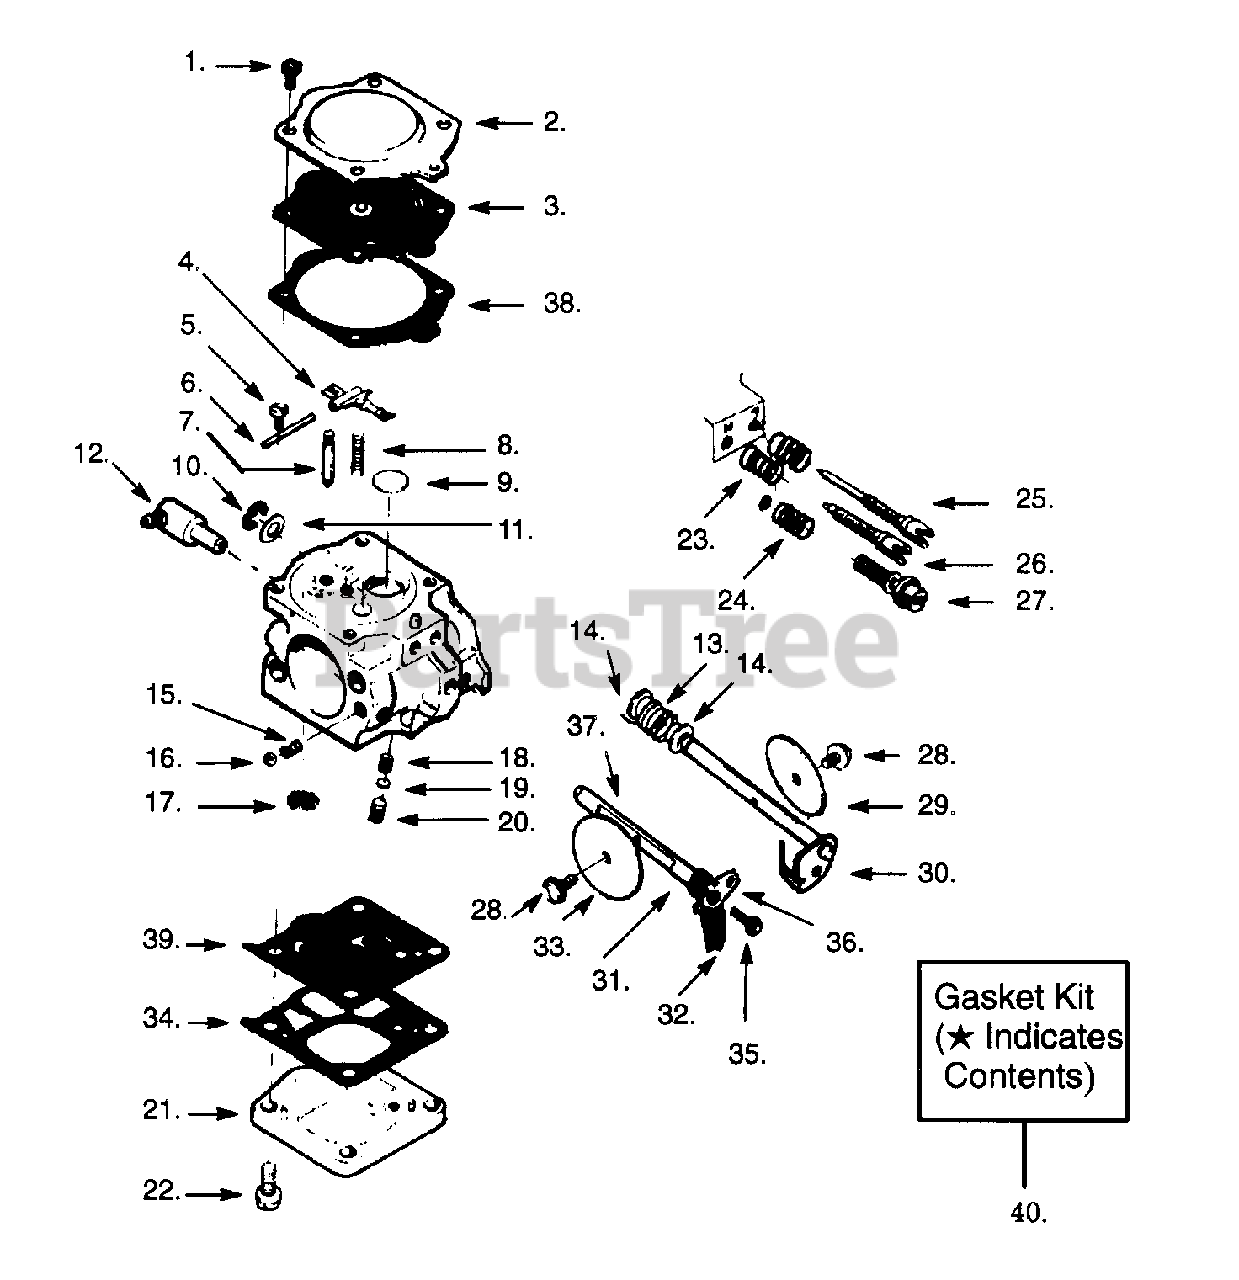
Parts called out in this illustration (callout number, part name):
1	Screw
3	Diaphragm
4	Metering Lever
7	Needle
8	Spring
13	Spring Return
17	Filter
21	Cover-Pump
23	Spring
24	Spring
25	Needle-Low
26	Needle-High
27	Idle Screw
30	Shaft Ass'y.
34	Gasket-Pump
37	Choke Shaft
38	Gasket
39	Diaphragm-Pump
40	Gasket Kit
